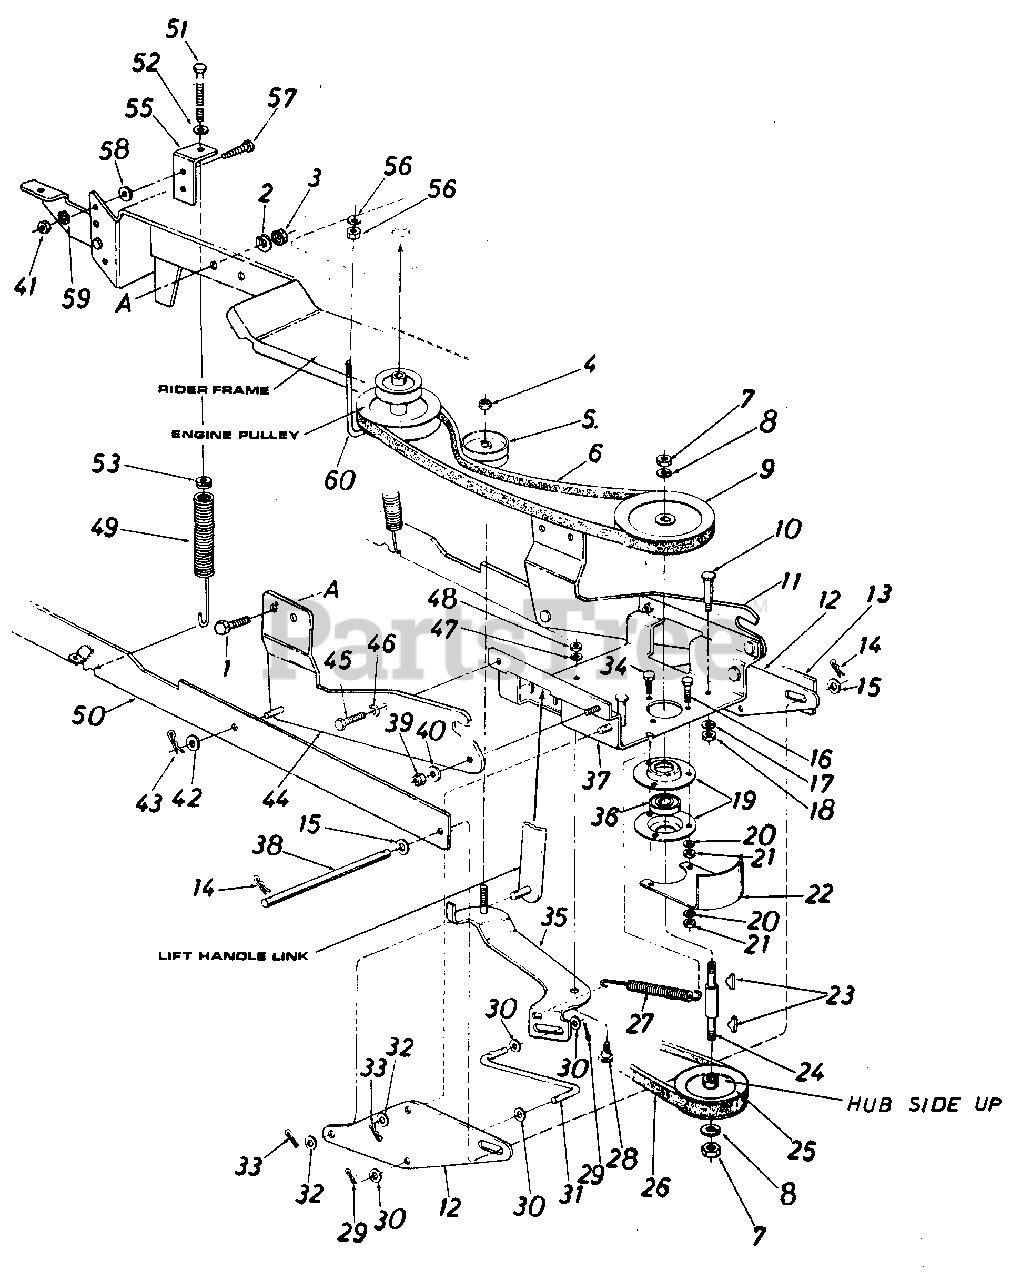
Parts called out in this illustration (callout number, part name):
1	HexScr. 1/4-28 x .75" Lg. Grade 5
2	L-Wash. 1/4" Scr.*
3	Hex Nut 1/4-28Thd.*
4	Hex Ins. Jam Nut 3/8-24 Thd.
5	Flat Idler3.25" O.D.
6	"V"-Belt 1/2 x 49" Lg.
7	Hex Jam Nut 5/8-11 Thd
8	L Wash. 5/8" I.D.*
9	6.50" O.D. x 5/8 Pulley
10	Shoulder Screw
11	Channel Supporting Brkt.-R.H.
12	Linkage Brkt.
13	Linkage Arm Ass'y.-R.H.
14	Intern. Cotter Pin .500" Dia. *
16	Hex Scr. 5/16-18 x 1.25"
17	L.-Wash. 3/8" Scr.*
18	Hex Nut 3/8-16 Thd.*
19	Bearing Housing
20	L.-Wash. 5/16" Scr.*
21	Hex Nut 5/16-18 Thd.*
24	Pulley Spindle
25	4.00 O.D. x 5/8 Pulley
26	"V"-Belt 1/2 x 85.2" Lg.
27	Extension Spring
28	Shoulder Screw
29	Cotter Pin 3/32" Dia. x l.00*
33	Inter. Cotter Pin .500" Dia. *
34	Hex Sems Scr. 5/16-18 x .75" Lg.*
35	Clutch Idler Brkt. Ass'y.
36	Ball Bearing
37	Channel Ass'y.
38	Lift Handle Shaft
39	Hex Ins. L-Nut 3/8-16 Thd.
41	Hex Nut 1/4-20Thd.*
43	Intern. Cotter Pin .500" Dia.*
44	Channel Supporting Brkt.-L.H.
45	Hex Scr. 3/8-16 x 1.00" Lg. *
46	L.-Wash. 3/8" Scr.*
47	L.-Wash. 5/16" Scr.*
48	Hex Nut 5/16-18 Thd.*
49	Helper Spring
50	Linkage Arm Ass'y.-L.H.
51	Hex Scr. 5/16-18 x 2.0" Lg Special
52	Fl.-Wash. 5/16" Scr.*
53	Spring Insert
57	Hex Bolt 1/4-20 x .75" Lg.*
58	Fl.-Wash. .264" I.D.
59	L.-Wash. 1/4" I.D.*
60	J-Bolt 5/16-18
